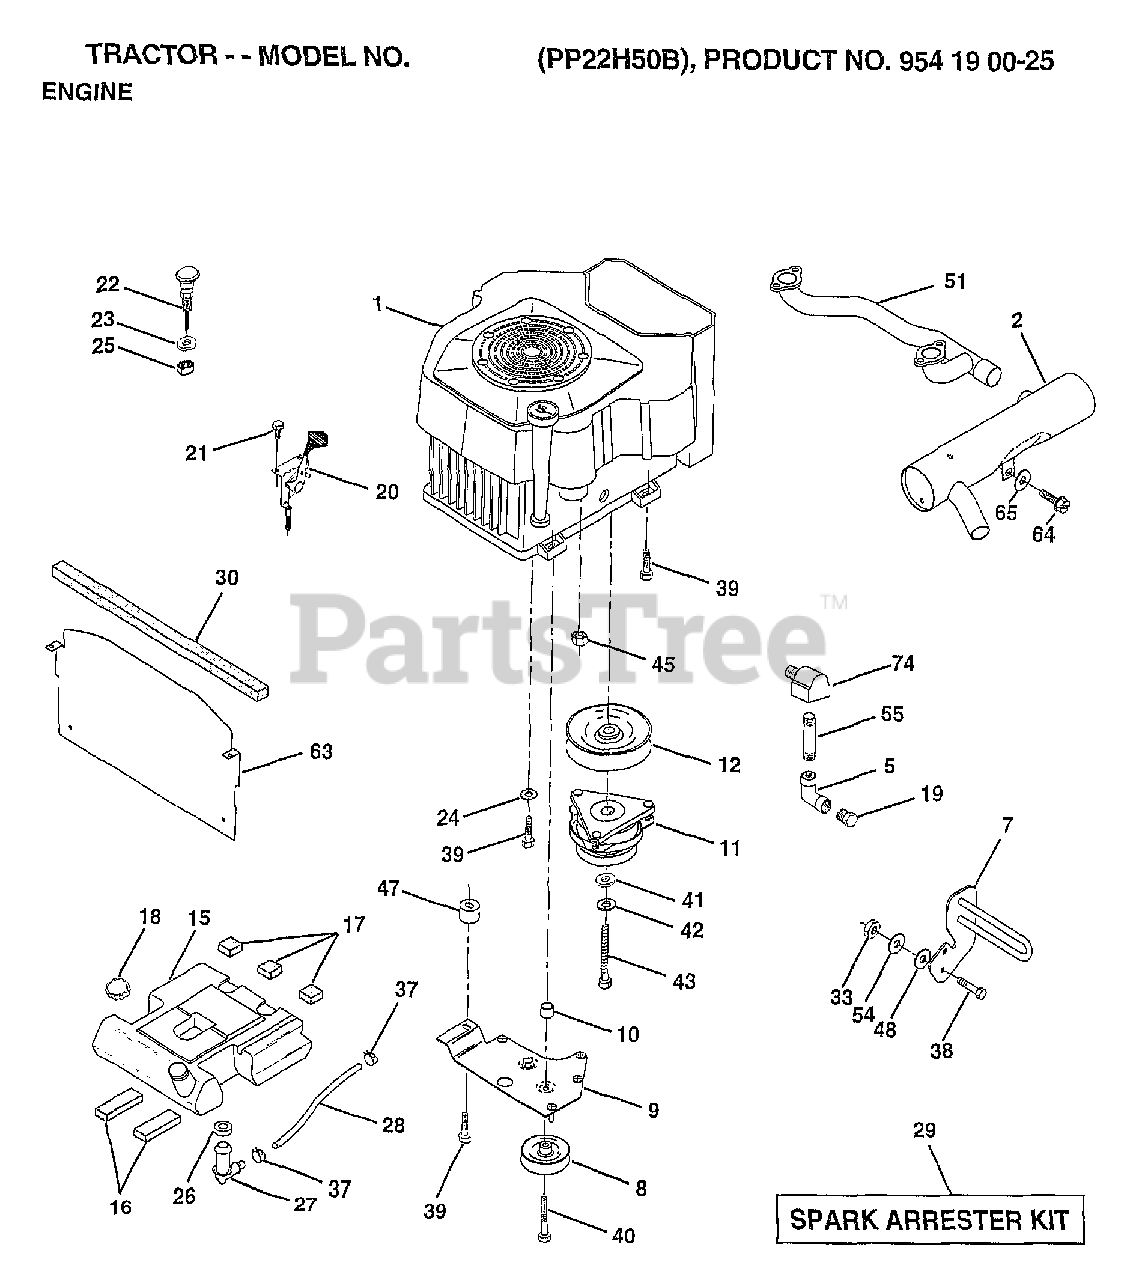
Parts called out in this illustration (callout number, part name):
2	MUFFLER SIDE1-1/8
5	ELBOW
7	GUARD.MUFFLER.ASM
9	KEEPER ASM BELT
10	BUSHING.
12	PULLEY.ENG.CLUTCH
15	TANK FUEL REAR
16	PAD IDLER TI
17	PAD-SPACER LT
18	CAP ASM FUEL
19	PLUG T
21	SCREW LT
22	CHOKE CONTROL
23	WASHER
24	LOCKWASHER
25	"NUT,KEPS 3/8-24IM"
26	BUSHING OUTLET T
27	STEM.TANK.FUEL
29	SPARK ARREST KIT
30	FOAM-STRIP LT
33	NUT
37	HOSE CLAMP
38	"BOLT,HEX"
39	SCREW.3/8-16X2.25
40	SCREW.TT.3/8-16X4
41	WASHER
42	LOCKWASHER
43	BOLT.7/16-20X4.25
45	NUT
47	SPACER.ENGINE
48	WASHER T
51	MANIFOLD PIPE VGT
54	WASHER
55	PIPE NIPPLE LT
63	HEAT.SHIELD.VGT.
64	SCREW THDROL 3/8-16
65	WASHER
74	ELBOW STREET BASS
